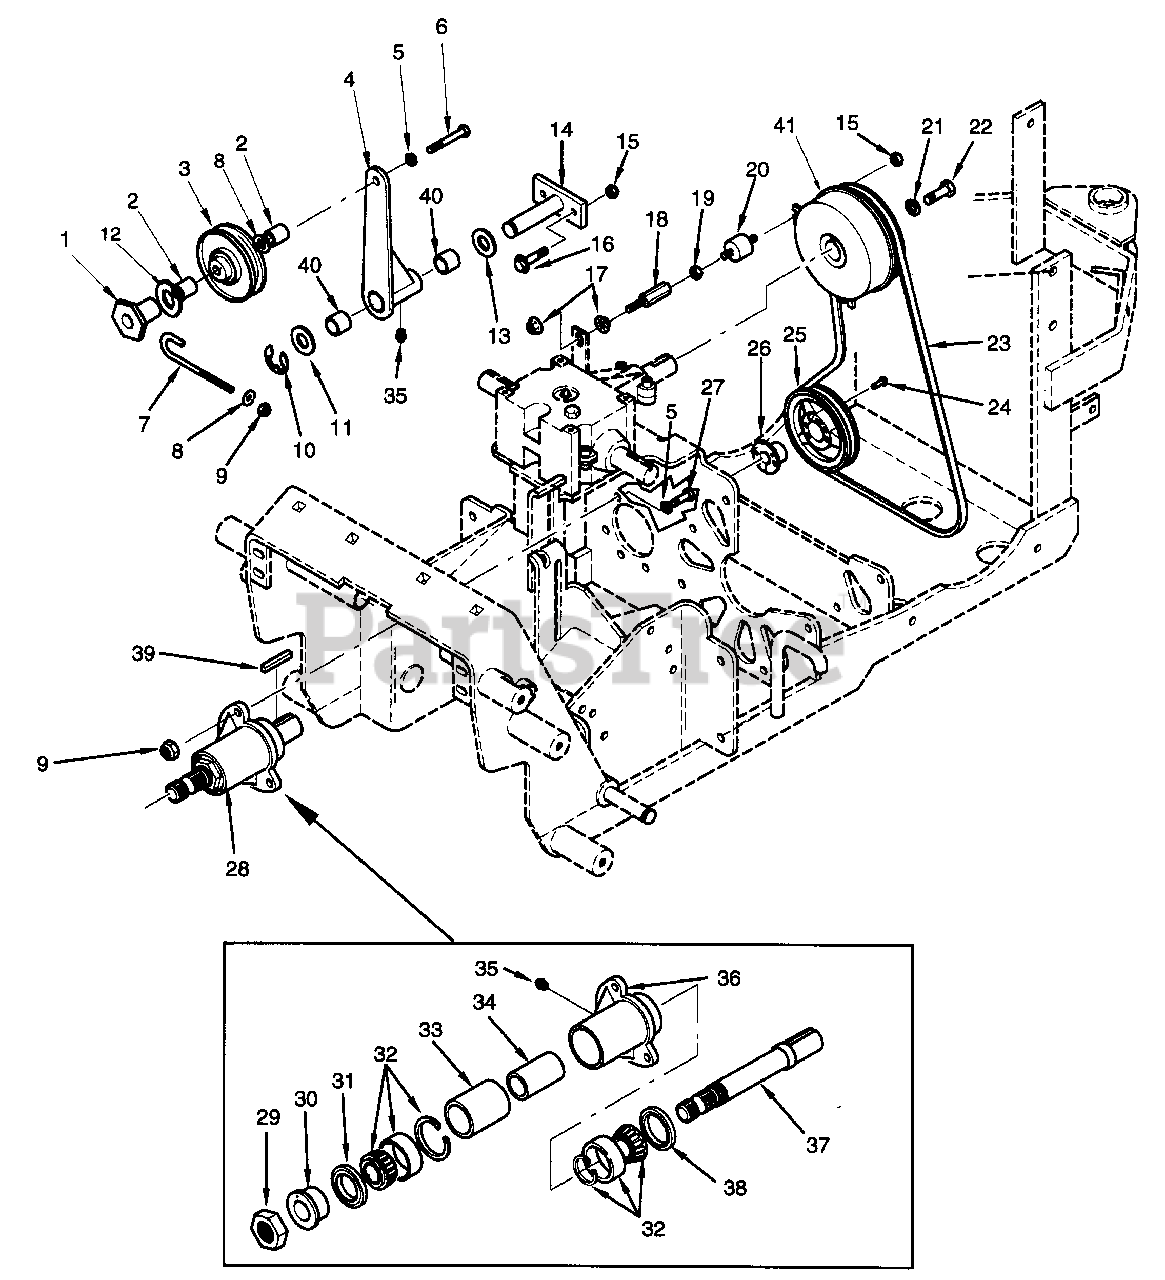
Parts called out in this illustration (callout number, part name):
1	NUT, SPECIAL
2	SPACER J-PULL ROD
3	PULLEY, IDLER
4	IDLER ARM, AUXILIARY DRIVE
5	LOCKWASHER, 3/8
6	BOLT, HEX HEAD, 3/8-16 X 3-1/4
7	J-PULL ROD
8	FLATWASHER, 3/8(.391 X .938 X .105)
9	HEX LOCKNUT, ELASTIC STOP, 3/8-16
10	RETAINING RING, .75 "E"
11	FLATWASHER, 3/4(.766 X 1.25 X .060)
12	WASHER
13	FLATWASHER, 3/4(.766 X 1.25 X .035)
14	PIVOT, AUXILIARY DRIVE IDLER
15	SERR. FL. HEX NUT, 5/16-18
16	SERR. FL. HEX HEAD CAPSCREW, 5/16-18 X 1.00
17	SERR. FL. HEX NUT, 7/16-14
18	PIN, CLUTCH ANTI-ROTATION
19	HEX NUT, 5/16-18
20	ISOLATOR, RUBBER
21	LOCKWASHER, 7/16
22	BOLT, HEX HEAD, 7/16-20 X 2-1/4
23	BELT, BLOWER DRIVE
24	SOCKET HEAD CAPSCREW, 1/4-20 X 1-3/8
25	PULLEY, 5.35 OD
26	HUB, TAPERED
27	BOLT, HEX HEAD, 3/8-16 X 1-1/4
28	SPINDLE ASSEMBLY, DRIVE SHAFT(INCLUDES29-38)
29	NUT, 1.06-18
30	SPINDLE BUSHING, BOTTOM
31	SEAL, 2.00 OD X 1.625 BORE
32	ROLLER BEARING ASSEMBLY
33	SPACER, OUTSIDE
34	SPACER, INSIDE
35	GREASE FITTING
36	SPINDLE HOUSING
37	SHAFT, PTO DECK DRIVE
38	SEAL, 2.00 OD X 1.50 BORE
39	KEY, 1/4 X 1/4 X 1-1/4
40	BUSHING, OILITE, .753 ID
41	ELECTRIC CLUTCH
